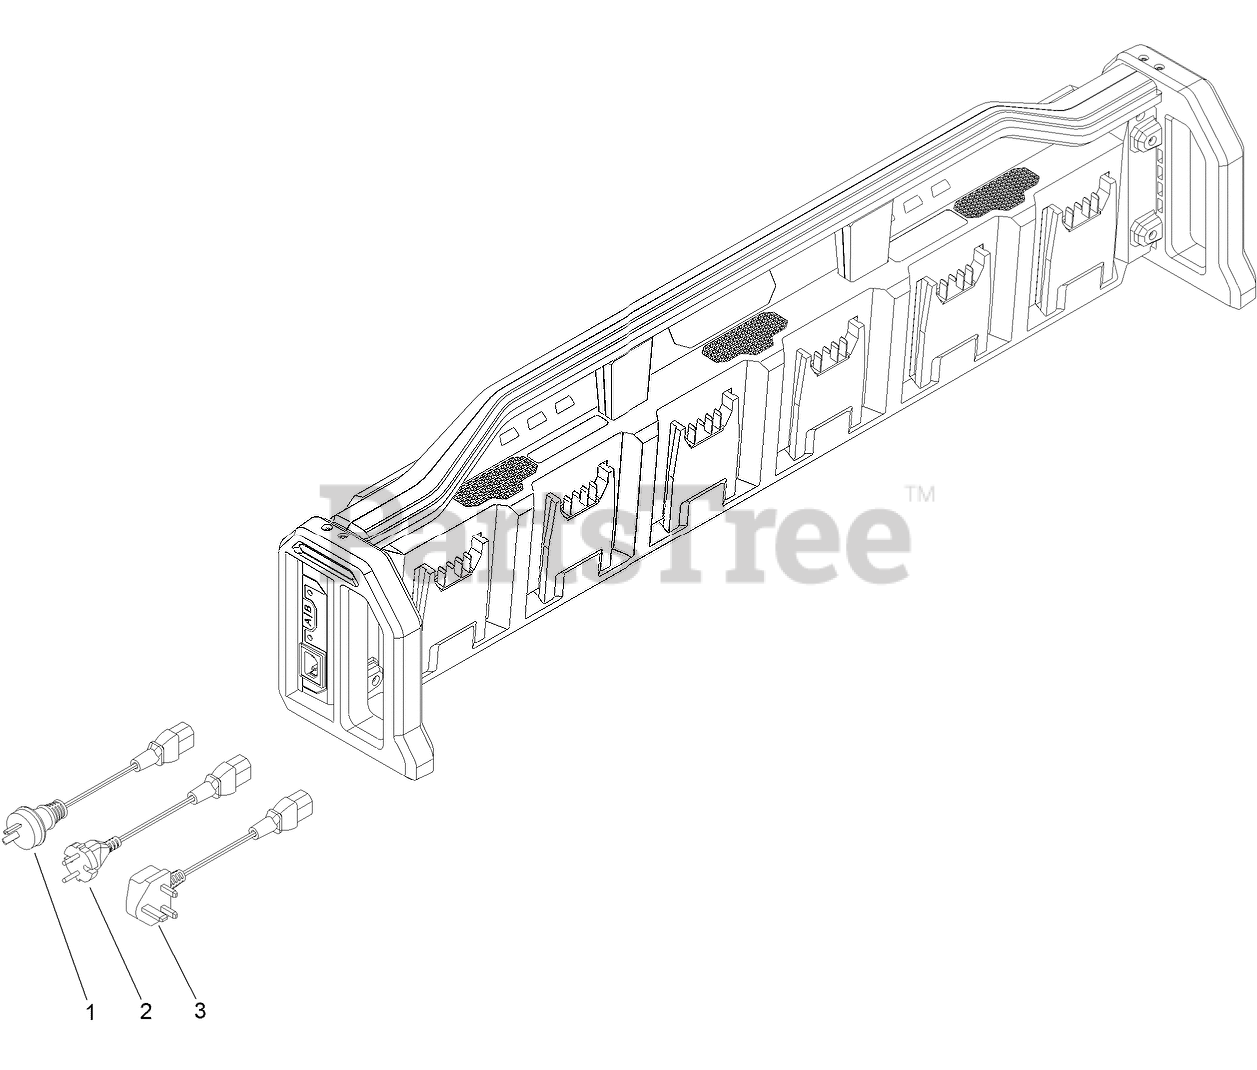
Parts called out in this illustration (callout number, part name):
1	CORD-CHARGER, SIX POD, AU/NZ
2	CORD-CHARGER, SIX POD, CE
3	CORD-CHARGER, SIX POD, UK
